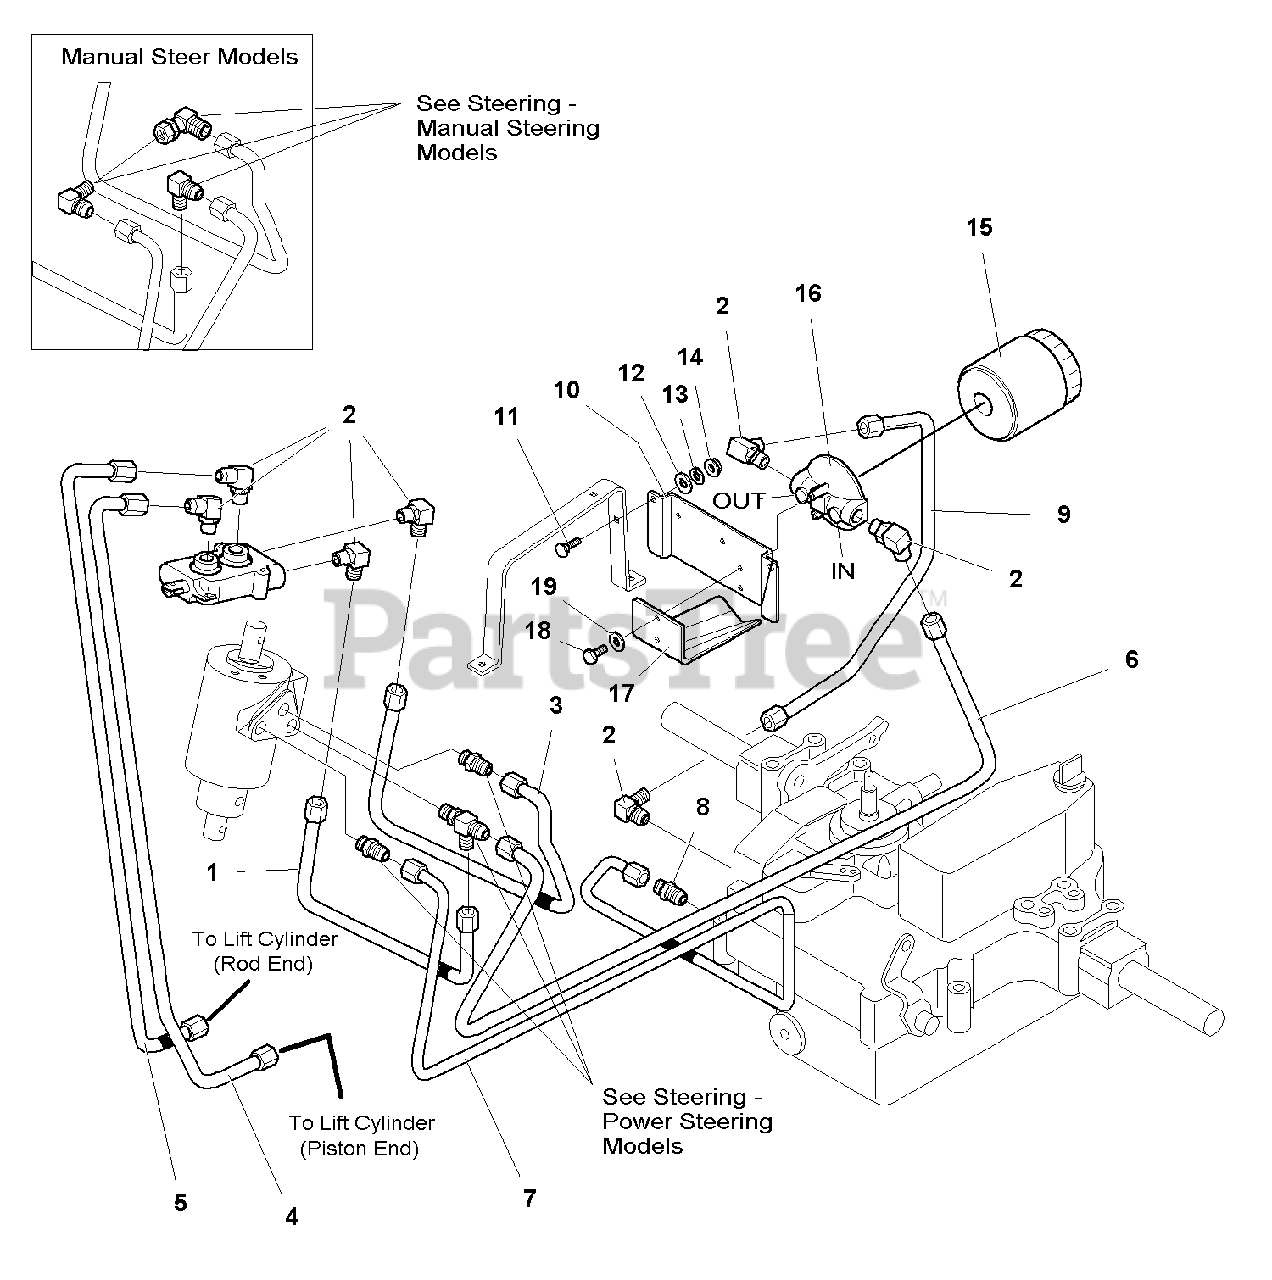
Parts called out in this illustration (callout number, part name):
1	HYDRAULIC LINE, Lift Valve Tee -- Torque OUT
2	FITTING, Elbow
3	HYDRAULIC LINE, Valve P -- Torque AUX
4	HYDRAULIC LINE, Valve A -- Cylinder Piston
5	HYDRAULIC LINE, Valve B -- Cylinder Rod
6	HYDRAULIC LINE, Torque Out -- Filter In
7	HYDRAULIC LINE, Torque IN -- Transmission Out
8	FITTING, Tube, Male, Short
9	HYDRAULIC LINE, Filter Out - Transmission In
10	BRACKET, Oil Filter
11	CARRIAGE BOLT, 5/16-18 x 3/4
12	WASHER, 5/16
13	WASHER, Lock, 5/16
14	NUT, Hex, 5/16-18
15	FILTER, Transmission Oil
16	BASE, Oil Filter
17	TROUGH, Hydraulic Oil Filter
18	CAPSCREW, Hex Head, 1/4-20 x 1/2
19	WASHER, Lock, 1/4
